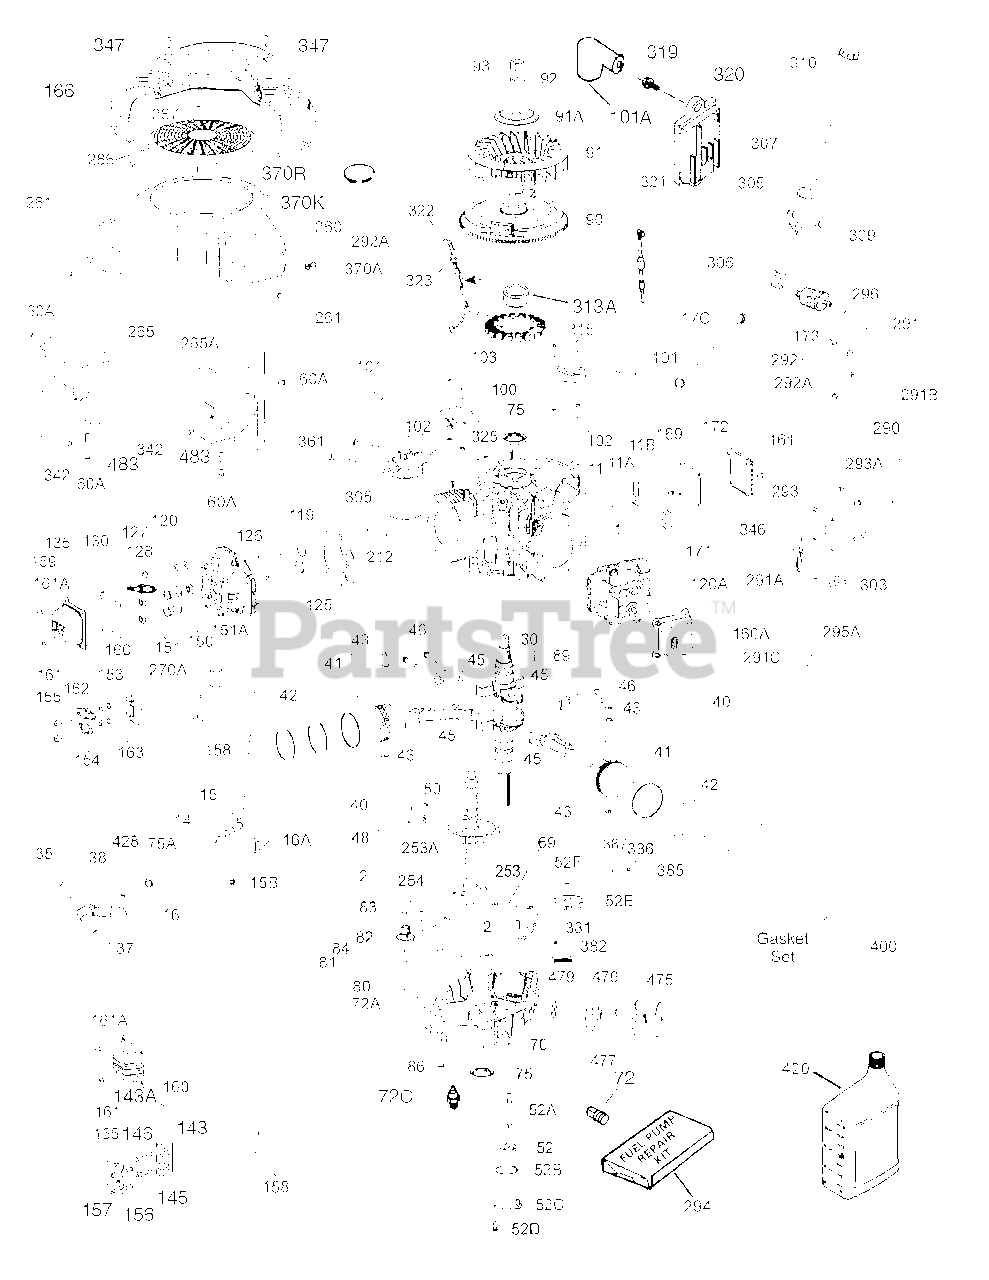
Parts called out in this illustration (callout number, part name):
11A	Breather Plate
11B	Screw, 10-32 x 7/16"
15	Governor Rod
15B	Screw, 1/4-20 x 5/8"
16	Governor Lever
16A	Governor Spring Bracket
16D	Governor Spring, Hi-speed
16E	Governor Idle Spring
16F	Bell Crank Lever
17C	Breather Tube Clamp
19	Throttle Spring
35	Screw, Carriage 1/4-20 x 1-1/2"
37	Lock Nut, 1/4-20
38	Retaining Ring
40	Piston, Pin & Ring Set (Std.)
40	Piston, Pin & Ring Set (.010"OS)
41	Piston & Pin Ass'y. (Std.) (Incl. 43)
41	Piston & Pin Ass'y.(.010"OS)(Incl.43)
42	Ring Set (Std.)
42	Ring Set (.010"OS)
43	Piston Pin Retaining Ring
45	Connecting Rod Ass'y. (Incl. 46)
46	Connecting Rod Bolt
48	Valve Lifter
50	Camshaft (MCR)
52	Oil Pump Ass'y.
52A	Oil Pump Shaft
52C	Oil Pump Cover (Incl. 52B)
52D	Screw, T-30 1/4-20 x 43/64"
52E	Oil Pump Gear
52F	Oil Pump Gear Retaining Ring
60A	Screw, 1/4-20 x 1/2"
69	Mounting Flange Gasket
70	Mounting Flange (Incl. 72,72A,75,80,381-387)
72	Oil Drain Plug, 3/18-18
72A	Oil Drain Plug, 3/8-18
72C	Oil Drain Valve
75	Oil Seal (1 in Ref 1, 1 in Ref 70)
75A	Oil Seal (Governor Shaft)
80	Governor Shaft
81	Washer (Governor Shaft)
82	Governor Gear Ass'y.
83	Governor Spool
84	Retaining Ring
86	Screw, 5/16-18 x 1-15/32"
90	Flywheel (Incl. 91 & 91A)
91A	Flywheel Retainer
92	Lock Washer, Flywheel (Under Ref. 93)
100	Solid State Ignition (Incl. 101)
101	Spark Plug Cover
102	Solid State Mounting Stud
103	Screw, T-15 10-24 x 15/16"
119	Cylinder Head Gasket
120	Cylinder Head, Opp. Breather Side
120A	Cylinder Head, Breather Side
125	Exhaust Valve (Std.)
126	Intake Valve (Std)
128	Belleville Washer
130	Screw, 5/16-18 x 2-1/2"(Head Mount)
135	Spark Plug (RN4C)
150	Valve Spring
151	Valve Keeper Retainer & Cap Set
153	Push Rod Guide
154	Rocker Arm Stud
159	Rocker Arm Cover Gasket
160	Rocker Arm Cover, Opp. Breather Side
160A	Rocker Arm Cover, Breather Side
161	Screw, T-30 1/4-20 x 1/2"
161A	Stud, Valve Cover Mounting
162	Rocker Arm Jam Nut, 5/16-24
163	Internal Lock Washer, 5/16"
169	Valve Cover Gasket
171	Breather Element
173	Breather Tube
173A	Breather Tube Grommet
173B	Breather Tube Fitting
177	Carbuertor Mounting Stud
184	Carburetor to Intake Pipe Gasket
185	Intake Pipe (Incl. 387A)
186	Governor Link
200	Control Bracket
207	Throttle Link
210	Conduit Clip
211	Screw, 10-32 x 3/8"
217	Control Lever
218	Screw, 10-32 x 1-1/4"
223	Screw, T-30 5/16-18 x 7/8"
224	Intake Pipe Gasket (Pipe to Head)
234	Lock Nut, 1/4-20
238	Screw, 10-32 x 7/16"
239	Air Cleaner Gasket
240	Air Cleaner Body Ass'y. (Incl. 239)
245	Air Cleaner Filter (Paper)
245B	Air Cleaner Pre-Filter (Poly)
246	Connector Bushing Link
250	Air Cleaner Cover
251	Wing Nut, 1/4-20 X 1-19/32" (A/C)
253	Compression Release Weight
253A	Compression Release Pin
254	Compression Release Spring
255	Control Cover
260	Blower Housing (Red)
261	Screw, 1/4-20 x 1/2"
265	Cylinder Head Cover, Opp. Breather
265A	Cylinder Head Cover, Breather Side
270A	Exhaust Port Liner
286	Flywheel Screen
287	Screw, T-20 8-18 x 1-15/32"
290	Fuel Line (17")
291	Fuel Line (8-1/4")
291A	Fuel Line (8-1/4")
291B	Fuel Line (8-1/4")
291C	Fuel Line (6-3/4")
292	Fuel Line Clamp
292A	Fuel Line Retainer
293A	Screw, 8-32 x 1-1/2"
294	Pulse Pump Repair Kit
295A	Fuel Fitting
296	Fuel Filter (Incl. 292)
303	Pulse Pump/Fuel Fitting
305	Oil Fill Tube
306	O-Ring (Oil Fill, Bottom)
307	O-Ring Oil Fill,(Top)
309	Screw, 1/4-20 x 57/64"
315	Alternator Coil (3/5 Split) (Incl.321- 323)
322	Connector Body
330	Wire Harness, Twin-Solenoid (Red), and Ignition Ground (Green)
330A	Twin-Solenoid Ground Wire (Black)
342	Screw, 1/4-20 x 9/16"(Ref. 240 & 265)
346	Fuel Pump Bracket
347	Screw, 10-32 x 27/32"
361	Screw, 5/16-18 x 2-3/8"
370A	Lubrication Decal
380	Carburetor (Incl. 184 & 428)
381	Screw, 8-32 x 27/64"
382	Oil Strainer Screen
383	Carburetor Baffle
384	Screw, 10-24 x 9/16" Self Tap
386	Pressure Release Spring
395	Electric Starter Motor (12 Volt)
400	Gasket Set (Incl. Items Marked PK in Notes)
406	Fuel Shut-Off Solenoid
476	Oil Filter Adaptor (Incl. 479)
477	Screw, T-30 5/16-18 x 1 3/32"
479	Oil Filter Adaptor Gasket
